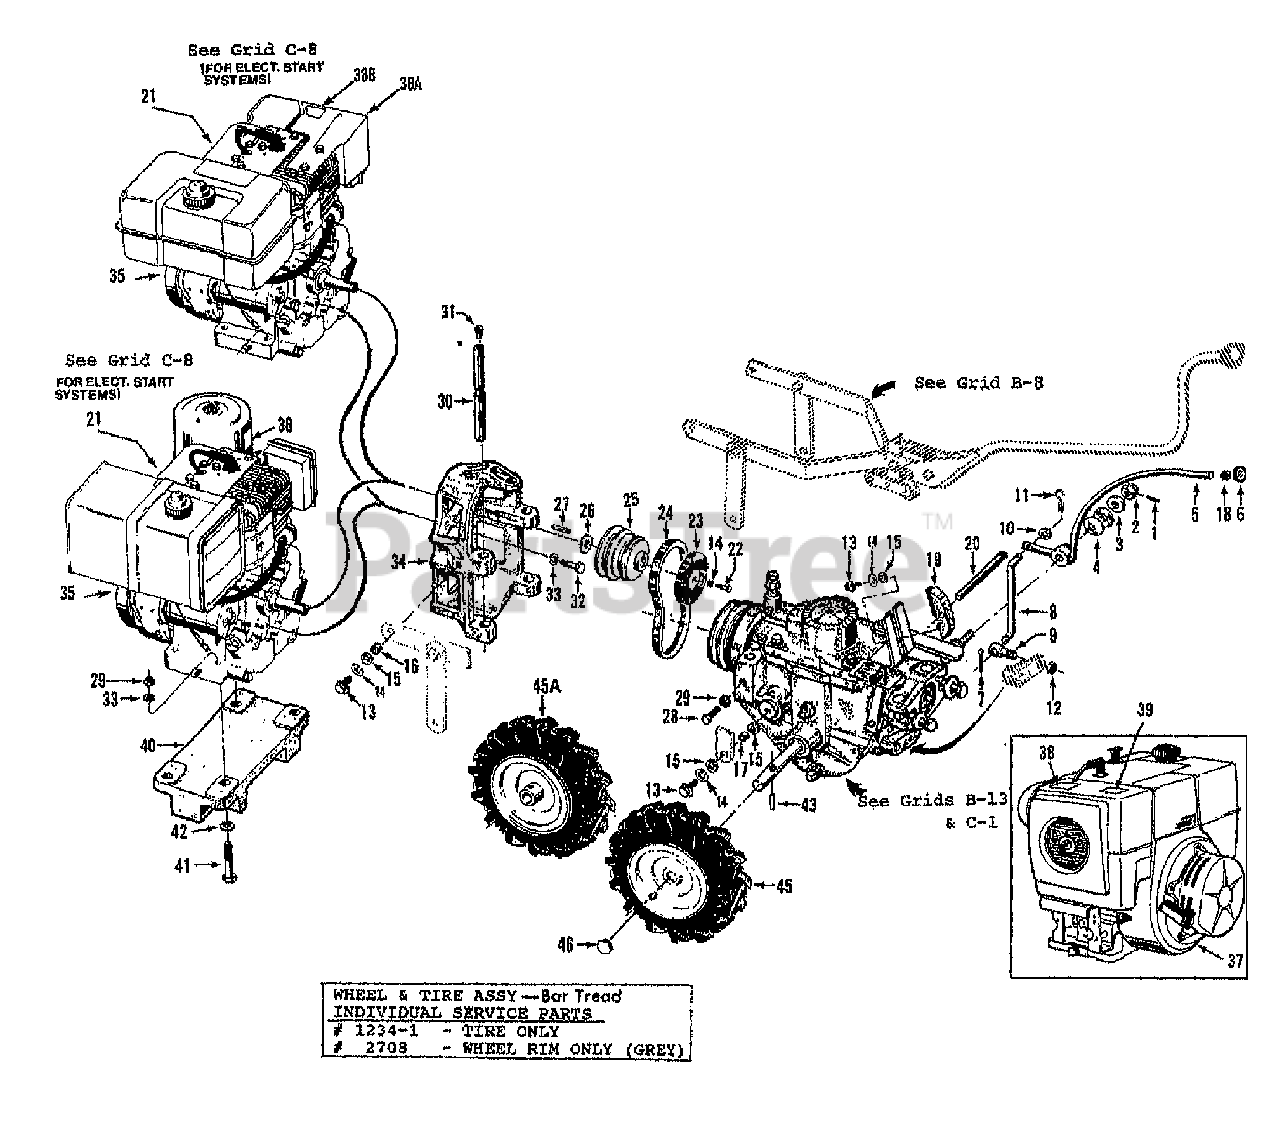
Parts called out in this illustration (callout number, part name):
1	PIN-SPRING .125 X 1
2	NUT-HEX 1/2-20 (SLOTTED)
3	WASHER-# SHOULDER ZP
4	WASHER-# 1.97X1X.118
5	LVR-W/KNOB (WHEEL SPEED) (INCL. 6 & 18)
6	KNOB-WHEEL SPEED HORSE (INCL. 18 & PLASTIC DECAL INLAY)
7	PIN-COTTER .094X1.0
8	ROD-CONNECTING
9	SWIVEL
10	WASHER-FLAT 5/16 SAE
11	PIN-CLIP .08
12	NUT-H/LK 5/16-18
13	SCR-HH 3/8-16X1.0 G5 ZP
14	WASHER-LK .375 @ DEPL
15	WASHER-FLAT 3/8 SAE
16	THIS REF. NO. NOT USED
17	BUSHING-.5X.375X.3
18	RING-TOLERANCE .5325 ID
19	KIT-ADJ BLOCK 4 SP (INCL. 13, 15 & 20)
20	BAR-ADJUST, 7" W/MEASURING GAUGE
21	DECAL-STARTING STABIL, B&S
22	SCR-HH 3/8-24X1.5 G5
23	KIT-ADJ BLOCK/REV DISC (INCL. 19)
23	DISC ONLY - REVERSE, RUBBER RIMMED
24	BELT-FORWARD DRIVE
25	PULLEY-ENG MACH
26	SHIM-1.0X.7656X.062
26	SHIM-1.0X.7656X.031
27	KEY-.188 SQ X 2.33
28	BOLT-HEX HD., 5/16-18x1", GR 5
29	NUT-HEX 5/16-18 ZP
30	BAR-ENG MTG W/CAP PLUG
31	PLUG-CAP (RED)
32	BOLT-HH 5/16-24X1.125 G5 ZP
33	WASHER-LK .312 ZP
34	MOUNT-MOTOR HSE OPC PNT
35	TILLER-7HP STD HORSE
35	TILLER-7HP EL HORSE
35	TLR-HORSE 8HP STD B&S
35	TILLER-8HP EL HORSE B&S
35	OBS-HORSE 7HP STD CA
35	OBS-HORSE 7HP ELC CA
35	TILLER-8 T/B STD HORSE I/P B&S
35	TILLER-8HP T/B EL HORSE B&S I/P
37	TILLER-8HP STD PRO HORSE
37	TILLER-8HP EL PRO HORSE
37	OBS-HORSE 8HP STD CA
37	OBS-HORSE 8HP ELC CA
37	TILLER-7HP T/B STD HORSE
37	TILLER-7HP T/B ELEC HORSE
38	DECAL-HOT SURFACE
38A	GUARD-MUFFLER
38B	DECAL-HOT SURFACE
39	DECAL-STABIL STARTING
40	WEIGHT-ENG ECONO PNT
41	SCR-HH 5/16-18X2.25 G5ZP
42	SPACER-.88X.385X.09 ZP
43	PIN-SPIROL .313 X 1.5
45	ASSM-TIRE&WHEEL LH GRAY
45A	ASSM-TIRE&WHEEL RH GRAY
46	CAP-HUB BLK PLASTIC (REPLACES 9145)
